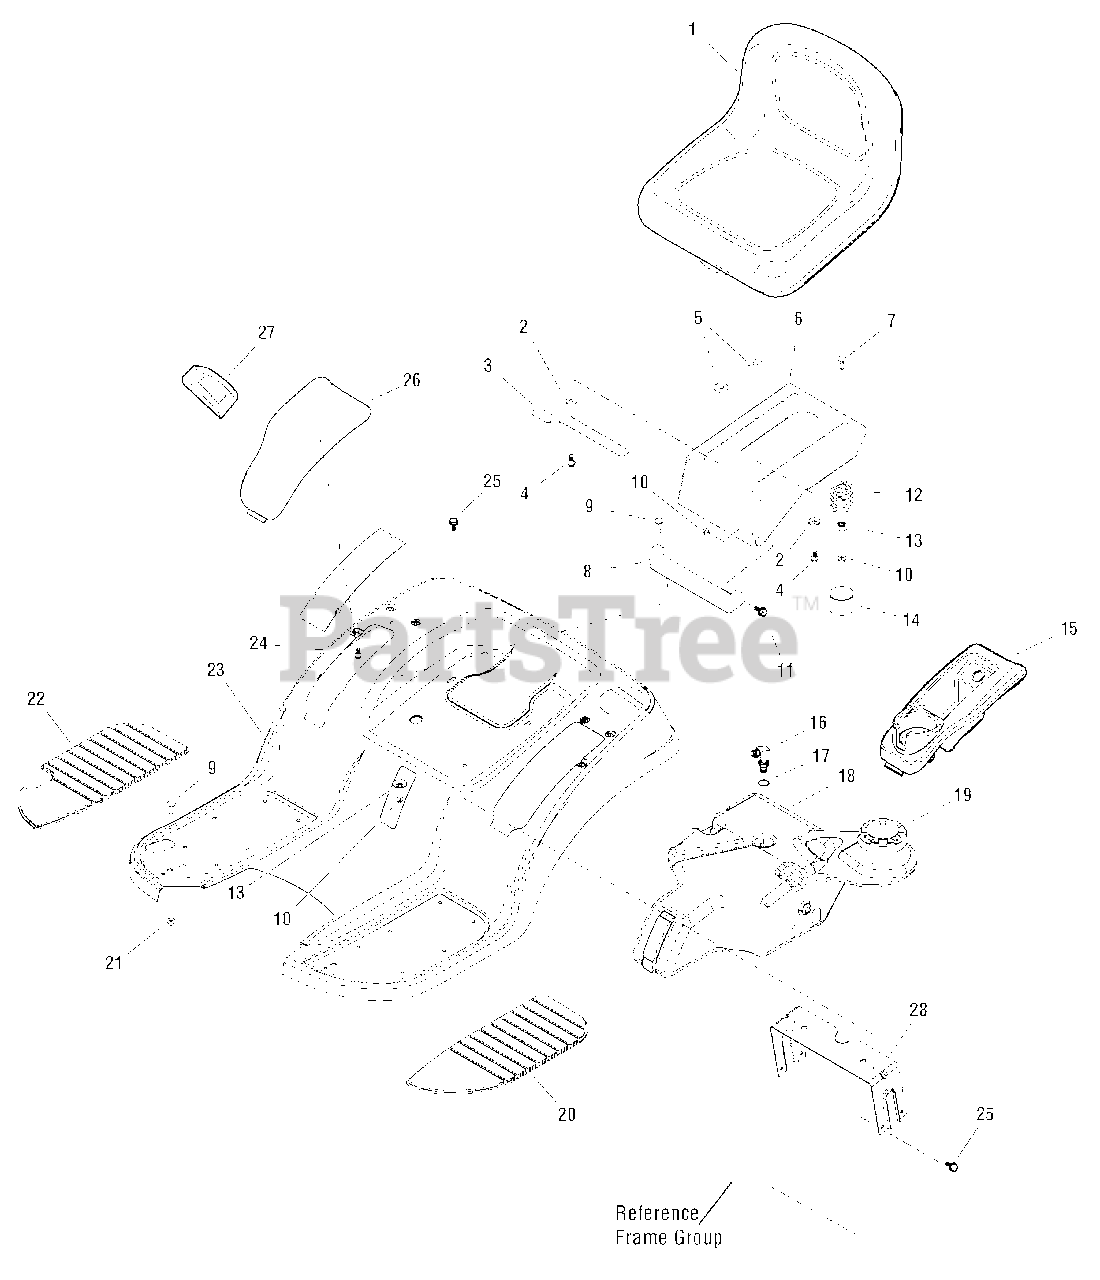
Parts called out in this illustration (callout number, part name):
1	SEAT, Hi Back, Steel Pan
1	SEAT, Low Back, Steel Pan
2	WASHER, Plain, 5/16
3	LATCH, Seat
4	CAPSCREW, Hex Head Flange Dog Point, 5/16-18 x 1
5	SPACER, 0.32 ID x 1-1/2 OD
6	SUPPORT, Seat
7	BOLT, Carriage, 5/16-18 x 3/4
8	PIVOT, Seat 10GA
9	BOLT, Carriage, 5/16-18 x 3/4
10	NUT, Hex Flange, ESNA, 5/16-18
11	BOLT, Shoulder, 5/16-18 G5
12	SPRING, Compression
13	WASHER, Spring Black
14	COVER, Spring
15	POD, LH Cup Holder
16	ELBOW FITTING
17	BUSHING
18	TANK, Fuel
19	CAP, Gas
20	PAD, Footrest L.H.
21	NUT, Hex, Flange Whizlock, 5/16-18
22	PAD, Footrest R.H.
23	DECK, Seat w/Footrests
24	CAPSCREW, Hex, Washer Head, Plastite, 1/4-20 x 1/2
25	CAPSCREW, Taptite, 5/16-18 x 5/8
26	POD, RH Lift Quadrant
27	GRIP, Lift
28	SUPPORT, Seat Deck
